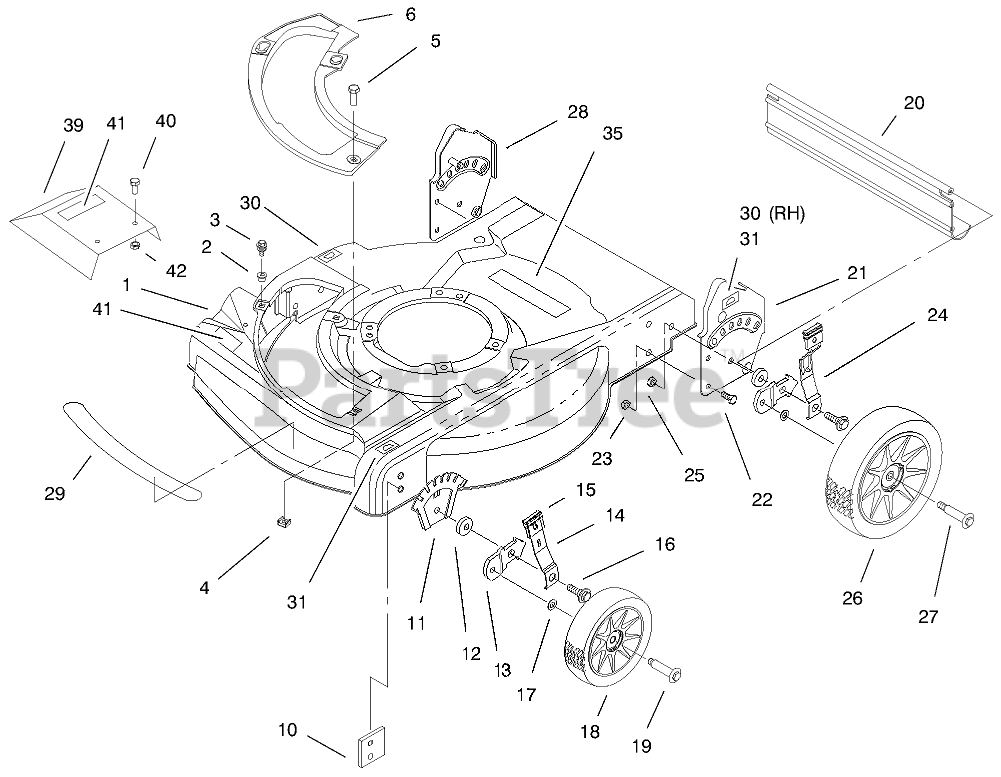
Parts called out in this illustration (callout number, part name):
1	ASM-Housing & Baffle (Incl. Ref. #2, 4, 29-31, 35, & 41)
2	NUT-CLIP
3	SCREW-SEMS
4	NUT-CAGE
5	SCREW-HWH
6	PLATE-OPENING, CHUTE
10	PLATE-BAFFLE
11	Plate H.O.C.
12	WASHER
13	Bracket-H.
14	ARM-FRONT SPRING
15	KNOB-LEVER, HEIGHT ADJUSTMENT
16	BOLT-SHOULDER
17	WASHER
18	WHEEL AND TIRE ASM
19	BOLT-SHOULDER
20	SHIELD-TRAILING
21	LH HANDLE BRACKET ASM
22	SCREW-HH
23	NUT-LOCK, NI
24	REAR SPRING ARM ASM
25	NUT-LOCK, NI
26	WHEEL ASM
27	BOLT-SHOULDER
28	RH HANDLE BRACKET ASM
29	DECAL - DECK
30	DECAL-HOC, RH
31	DECAL-HOC, LH
35	DECAL-DANGER
39	Guard-Plate (Incl. Ref. #41)
40	SCREW-HWH
41	DECAL - WARNING
42	NUT-LOCK, NI
